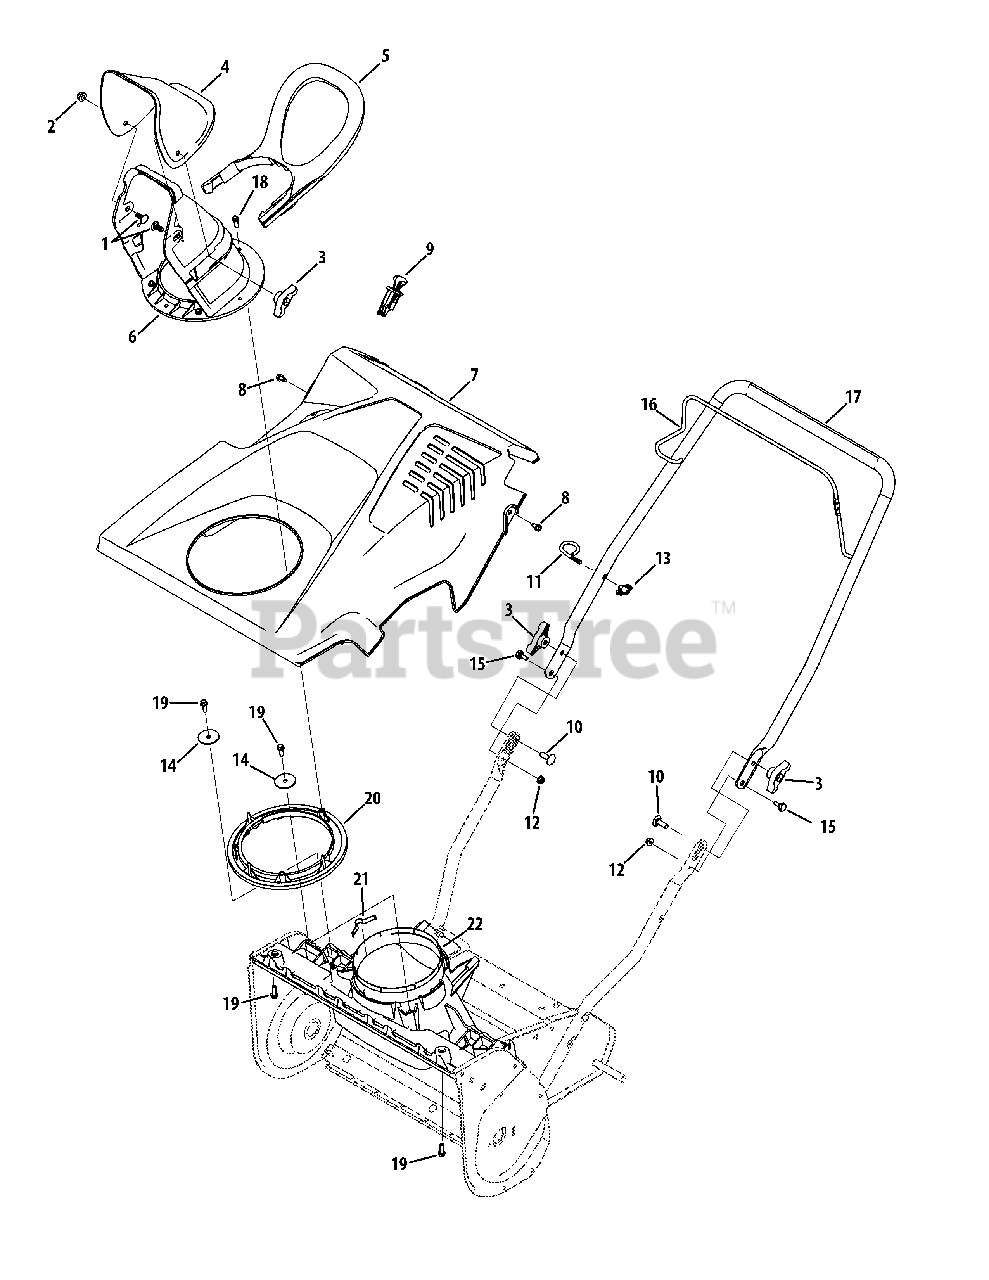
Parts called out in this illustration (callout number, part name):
1	Carriage Bolt, 5/16-18 x .750
2	Flange Lock Nut, 5/16-18
3	Wing Knob, 5/16-18
4	Upper Chute
5	Chute Handle
6	Lower Chute
7	Cover Assembly
8	Hex Washer Screw, 1/4-20 x .625
9	Ignition Switch Assembly
10	Carriage Screw, 5/16-18 x 1.00
11	Eye Bolt, 1/4-20
12	Flange Lock Nut, 1/4-20
13	Handle Knob, 1/4-20
14	Flat Washer, .28 x 1.51 x .066
15	Shoulder Screw, 1/4-20 x .375 x .148
16	Auger Control
17	Upper Handle
18	Hex Washer Screw, 1/4 x .750
19	Hex Washer Screw, 1/4-15 x .750
20	Chute Ring
21	Chute Adjustment Spring
22	Chute Adapter
